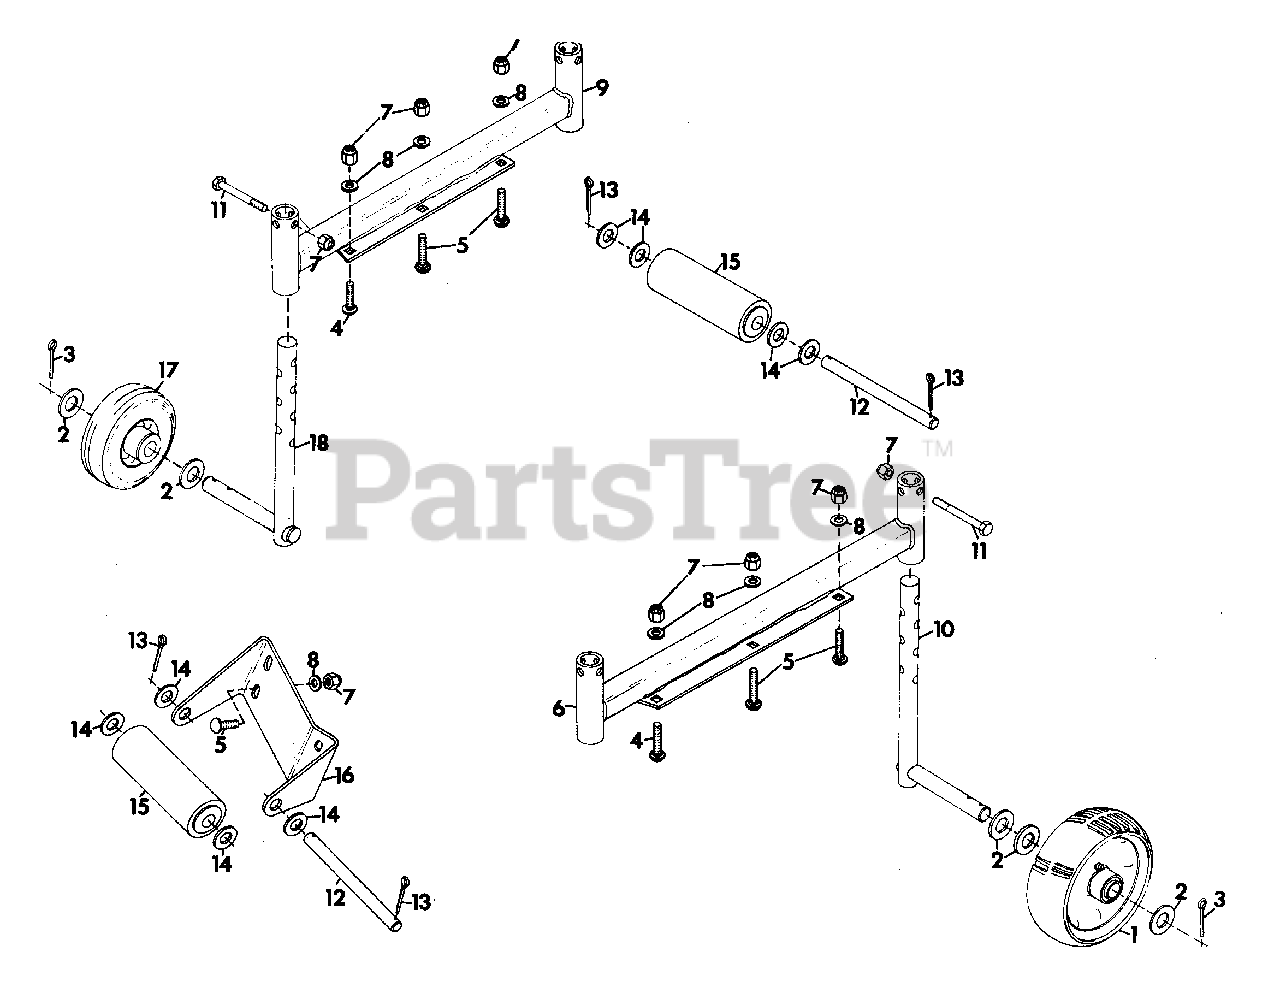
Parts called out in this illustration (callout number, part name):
1	Gage Wheel 8.250
2	Washer Flat .813 x 1.375 x .100
3	Pin, Cotter; 1/8 x 1.500
4	Bolt 3/8-16 x 1.000 RD HD SQ NK
5	Bolt 3/8-16 x .875 RD HD SQ NK
6	Support Left
7	Nut, Lock; 3/8-16
8	Washer, Flat .406 x .812 x .065
9	Support Right
10	Axle for 8.250 Gage Wheel
11	Bolt, Hex 3/8-16 x 2.000
12	Shaft, Center Roller
13	Pin, Cotter 1/8 x 1.250
14	Washer, Flat .656 x 1.312 x .095
15	Roller, Gage
16	Bracket, Roller Front
17	Gage Wheel 6.000
18	Axle for 6.000 Gage Wheel
